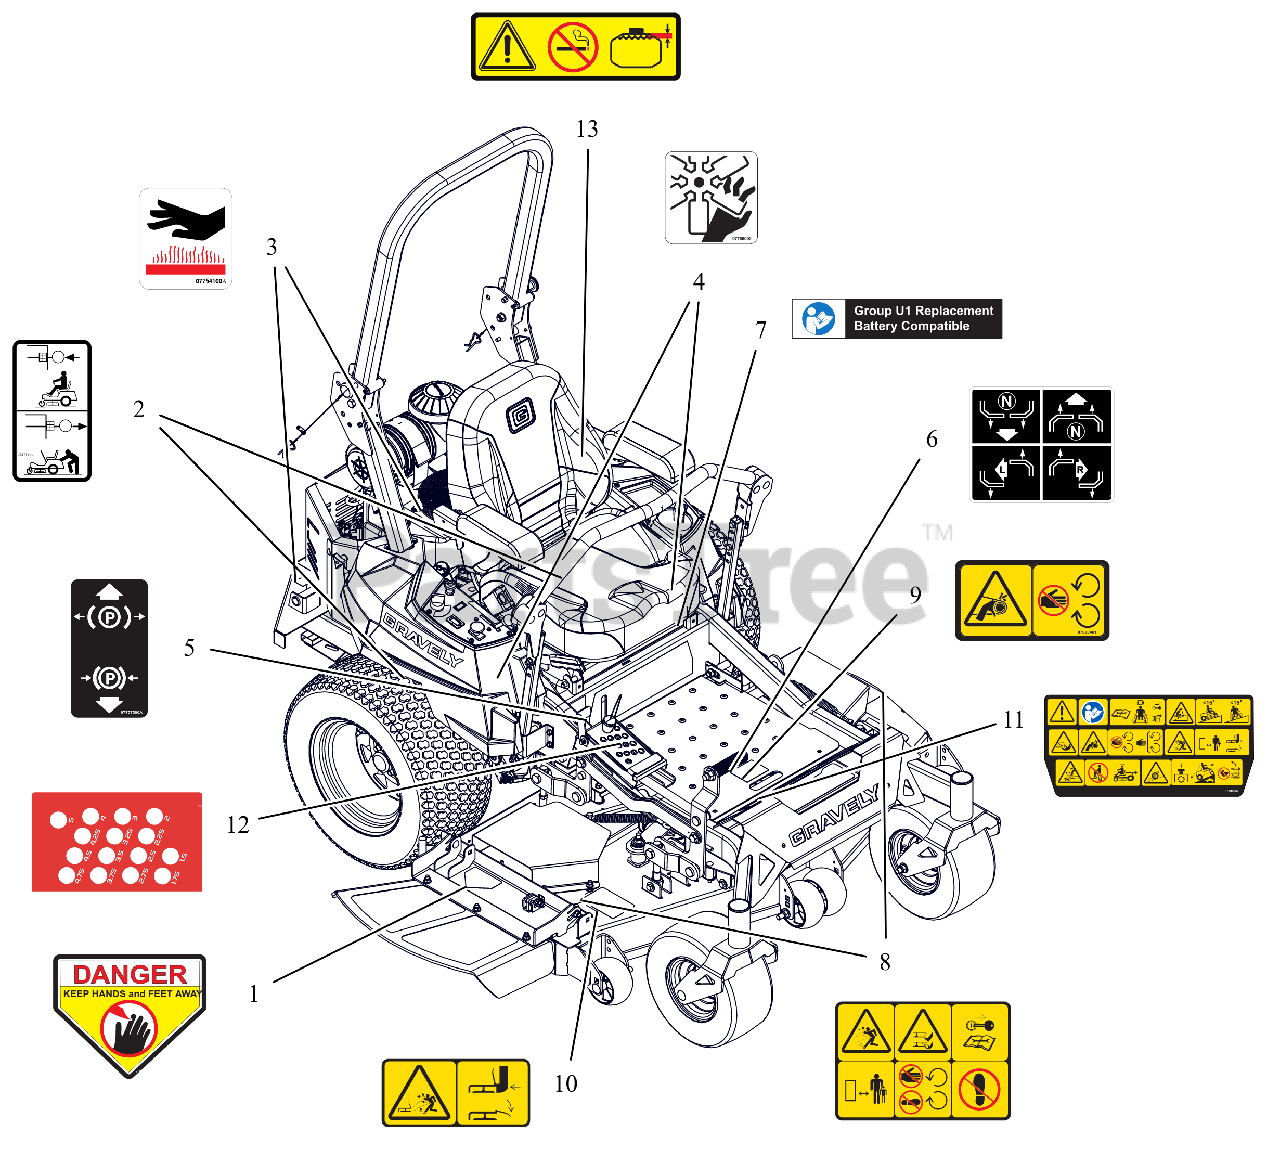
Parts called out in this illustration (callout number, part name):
1	DECAL, DANGER
2	DECAL, TRANSMISSION DISCONNECT
3	DECAL, HOT SURFACE
4	DECAL, DANGER FAN
5	DECAL, PARKING BRAKE LEVER
6	DECAL, INSTRUCTIONAL-STEERING
7	DECAL, U1 BATTERY REPLACEMENT
8	DECAL, SAFETY - MOWER DECK
9	DECAL, SAFETY - GUARDING
10	DECAL, SAFETY - DECK GUARDING
11	DECAL, MAIN SAFETY
12	DECAL - HOC
13	DECAL, FUEL WARNING
